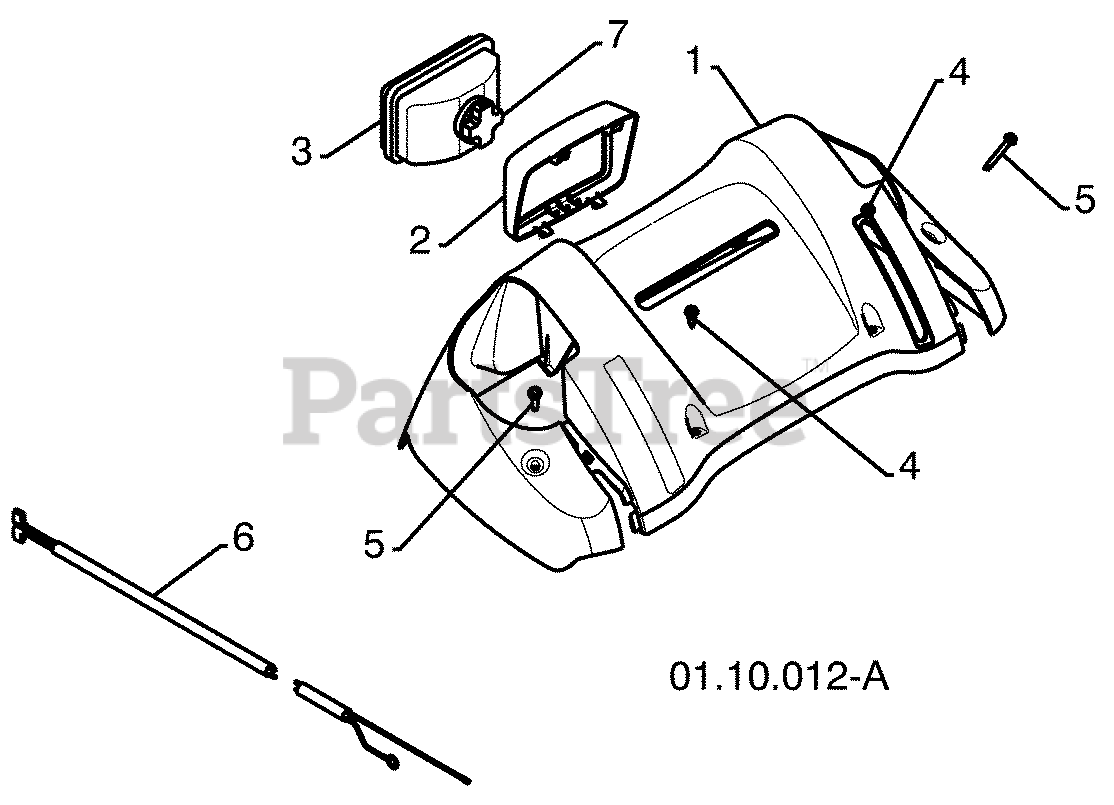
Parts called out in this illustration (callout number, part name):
1	CONSOLE PANEL GRAY
2	HEADLIGHT BEZEL GRAY
3	FLOOD HEADLIGHT
4	SHOULDER SCREW 10-24 X .625
5	SCREW 10-24 X 1.25
6	WIRE HARNESS
